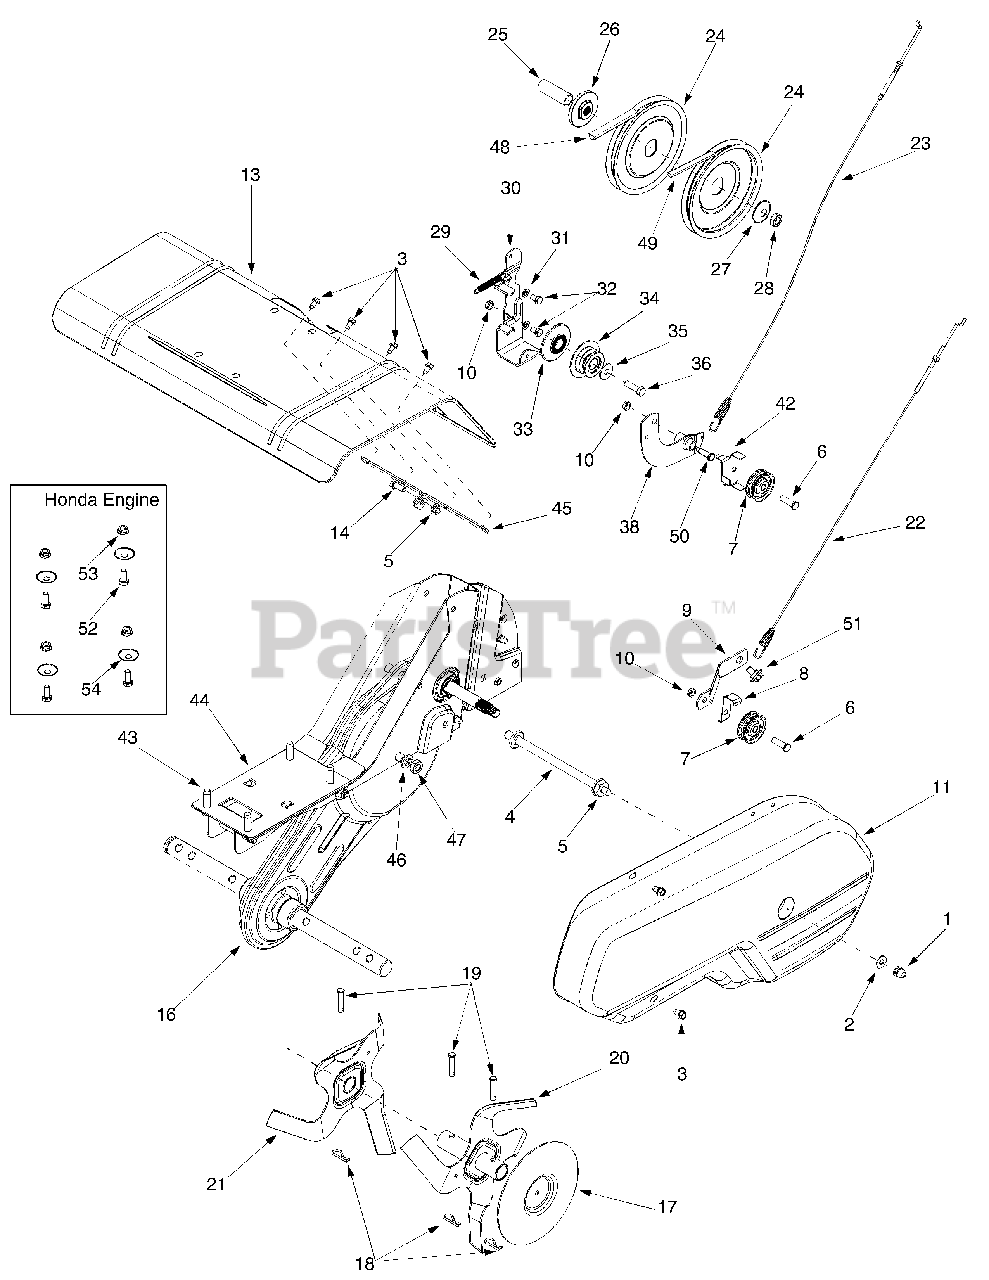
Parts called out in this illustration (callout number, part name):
1	Hex L-Stop nut 1/4-28
2	Flat Wash.266" I.D. x.625" O.D.
3	Hex Washer TT-Tap Scr. 1/4-20 x.5"
4	Belt Cover Bolt
5	Hex Flange Top L-Nut 5/16-18
6	Hex Hd. Scr. 3/8-16 x 1.25" Lg.
7	Flat Idler Pulley 2.12" O.D.
8	Idler Belt Keeper
10	Hex Cent. Jam Nut 3/8-16 Thd.
14	Hex Hd. Cap Scr. 5/16-18 x.75" Lg
16	Chain Case Assembly Complete
18	Internal Cotter Pin
19	Clevis Pin
22	Forward Clutch Cable
23	Reverse Clutch Cable
24	Fl-Pulley 6" Dia.
25	Spacer.64" Dia. x 2.4" Lg.
26	Pulley Mounting Adapter
27	Bell-Wash.525" I.D. x 1.5" O.D.
28	Hex Jam Nut 1/2-20 Thd.
29	Return Spring
31	Lock Washer 5/16
32	Hex Bolt 5/16-24 x.625"
33	Engine Inner Half Pulley
34	Reverse Engine Pulley
35	Bell Washer.396" I.D. x 1/14" O.D.
36	Hex Bolt 3/8-24 x 1.00"
38	Reverse Arm Assembly
43	Hex L-Wash. TT-Tap 3/8-16 x 1.25"
46	L-Wash. 7/16" I.D.
47	Hex Nut 7/16-20 Thd.
48	V-Belt (Forward) 1/2 x 41.9"
49	V-Belt (Reverse) 3/8 x 45.68"
50	Shld. Screw.498 x 1.445
51	Shld. Screw.560 x.165
52	Screw 5/16-18 x 1.50
53	Hex Nut 5/16-18
54	Bell Washer
